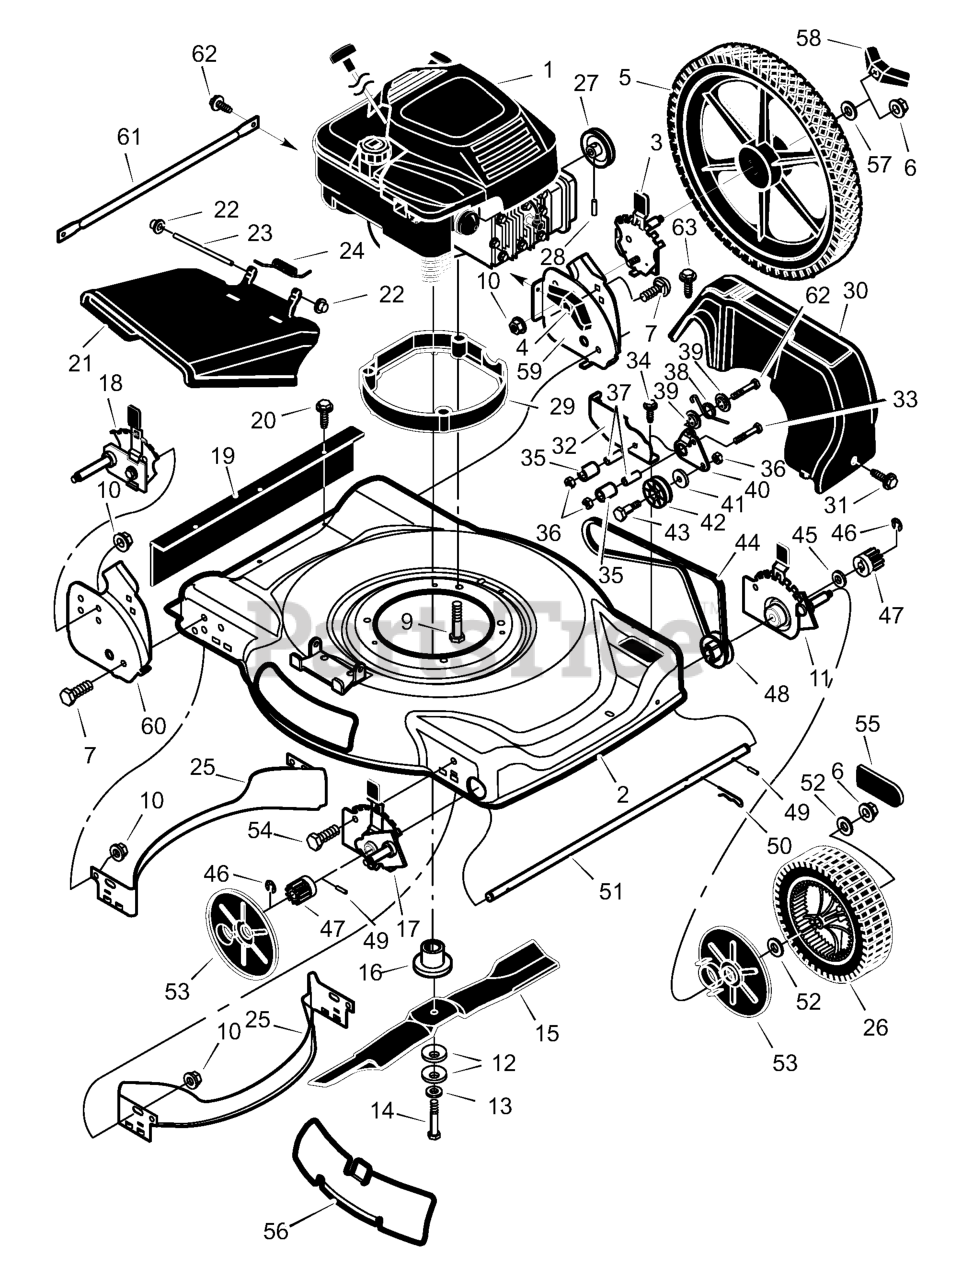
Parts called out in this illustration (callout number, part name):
1	Engine *
2	Housing
3	Height Adjuster, Left Rear
5	Wheel and Tire, Rear
6	Locknut, Flange
7	Bolt, Carriage
9	Bolt, Engine
10	Nut
11	Height Adjuster, Left Front
12	Washer, Belleville
14	Bolt, Hex
15	Blade, Mulcher
16	Adapter, Blade
17	Height, Adjuster, Right Frt.
18	Height, Adjuster, Right Rr.
19	Guard, Rear
21	Deflector, Chute
22	Push-On Cap
23	Pin, Pivot
26	Wheel and Tire, Drive
28	Pin, Spring
29	Base, Engine
30	Cover, Belt (Black)
32	Bracket, Idler Support
35	Idler, Backside
36	Locknut
37	Bearing
40	Arm, Pivot
42	Pulley, Idler
43	Bolt, Shoulder
44	Belt, Briggs & Stratton
46	Ring, Retainer
47	Gear, Pinion
49	Pin, Drive
50	Pin, Hair
52	Washer
53	Cover, Dust
54	Bolt
55	Hub Cap
56	Plate, Mulch
58	Knob, Axle
59	Bracket, Left Handle
60	Bracket, Right Handle
